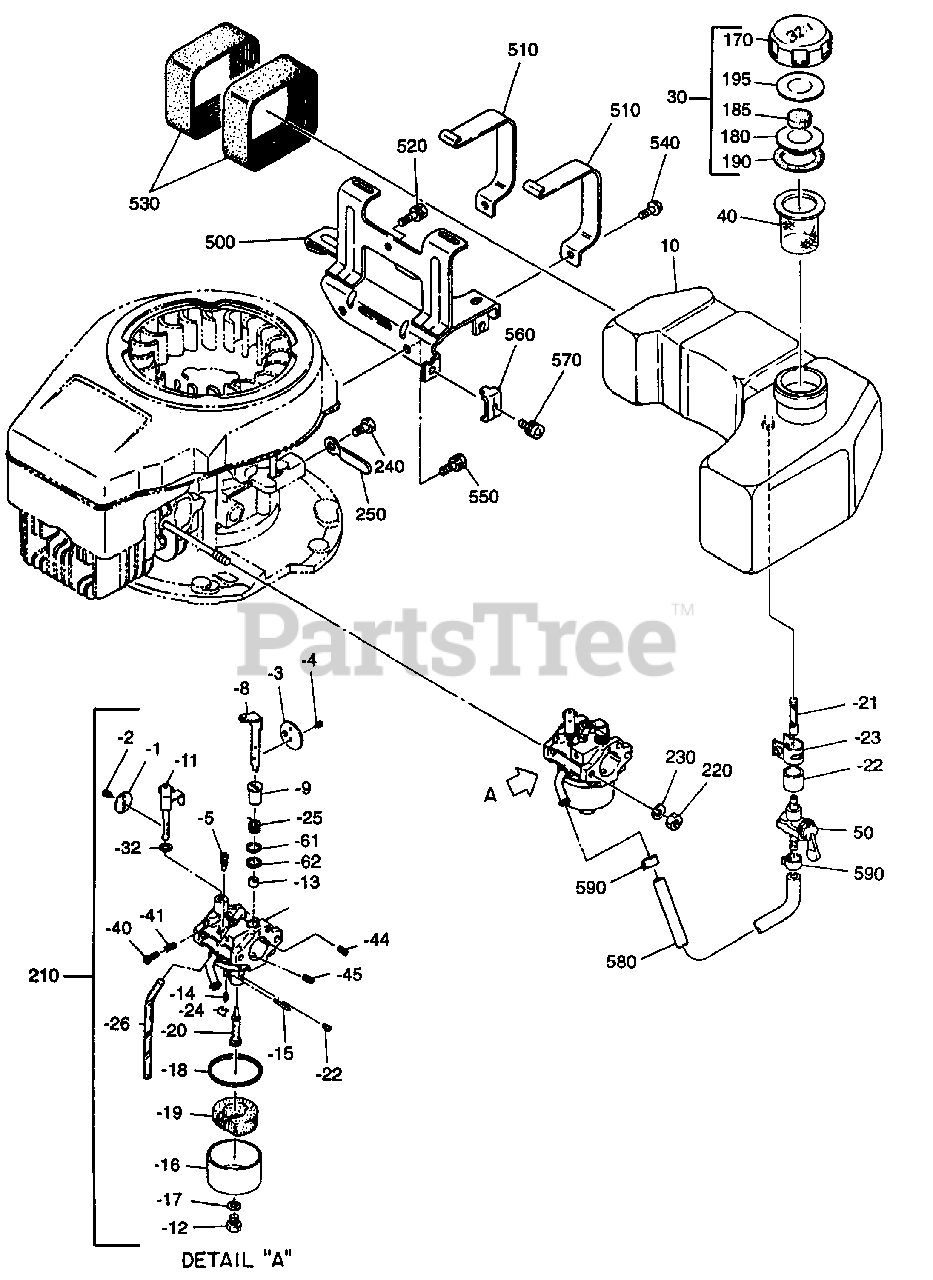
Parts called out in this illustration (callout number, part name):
1	THROTTLE VALVE
3	CHOKE VALVE
8	CHOKE LEVER
10	FUEL TANK CP
11	SHAFT AY (THROTTLE)
14	NEEDLE VALVE
16	FLOAT CHAMBER BODY
18	CHAMBER PACKING
20	MAIN NOZZLE
21	FILTER V-STD
22	JOINT PIPE V-STD
23	HOSE BAND AY V-STD
30	FUEL TANK CAP CP
32	SEAL
40	FUEL FILTER
50	FUEL STRAINER ASSY
190	GASKET (TANK CAP)
195	PARTITION PLATE
210	CARBURETOR ASSY
230	SPRING WASHER
500	FUEL TANK BRACKET CP
510	TANK BAND CP
520	BOLT AND WASHER ASSY
530	RUBBER BAND (TANK)
540	FLANGE BOLT
550	BOLT AND WASHER ASSY
570	BOLT AND WASHER ASSY
580	RUBBER PIPE
